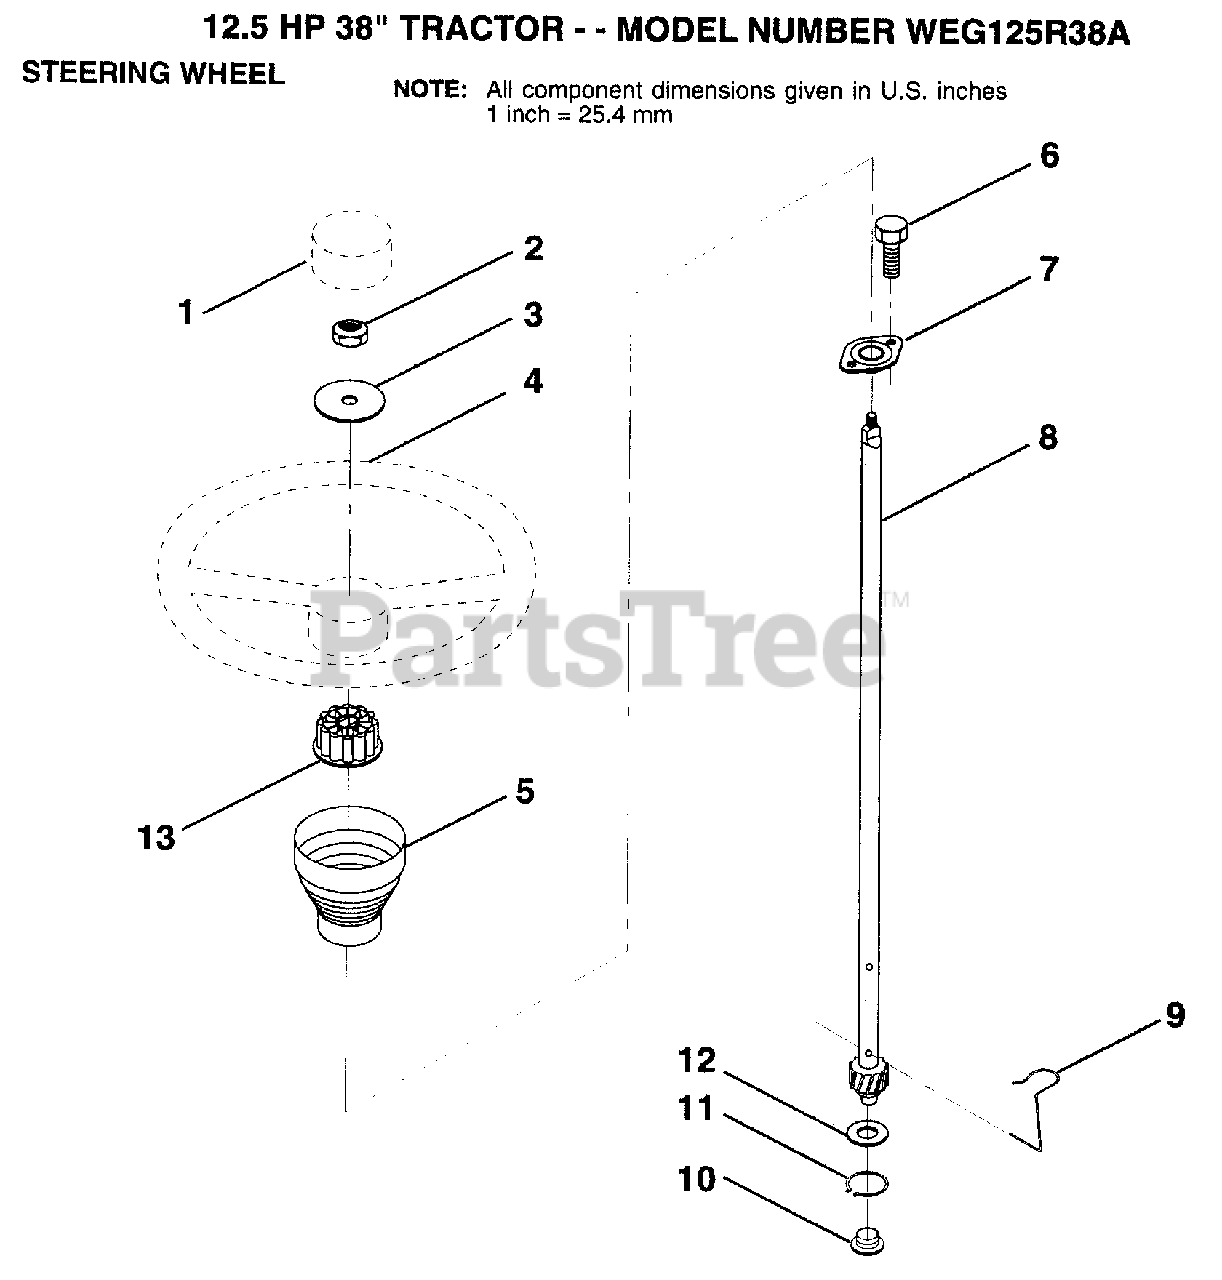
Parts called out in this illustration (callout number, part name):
1	ST WHL INSERT CAP
2	GRIPCO NUT
3	WASHER T
5	SLEEVE STEERING
9	STEERING CLIP
10	BUSHING STEER LWR
11	RING
12	WASHER LT
13	ADAPTER-WHEEL LT
